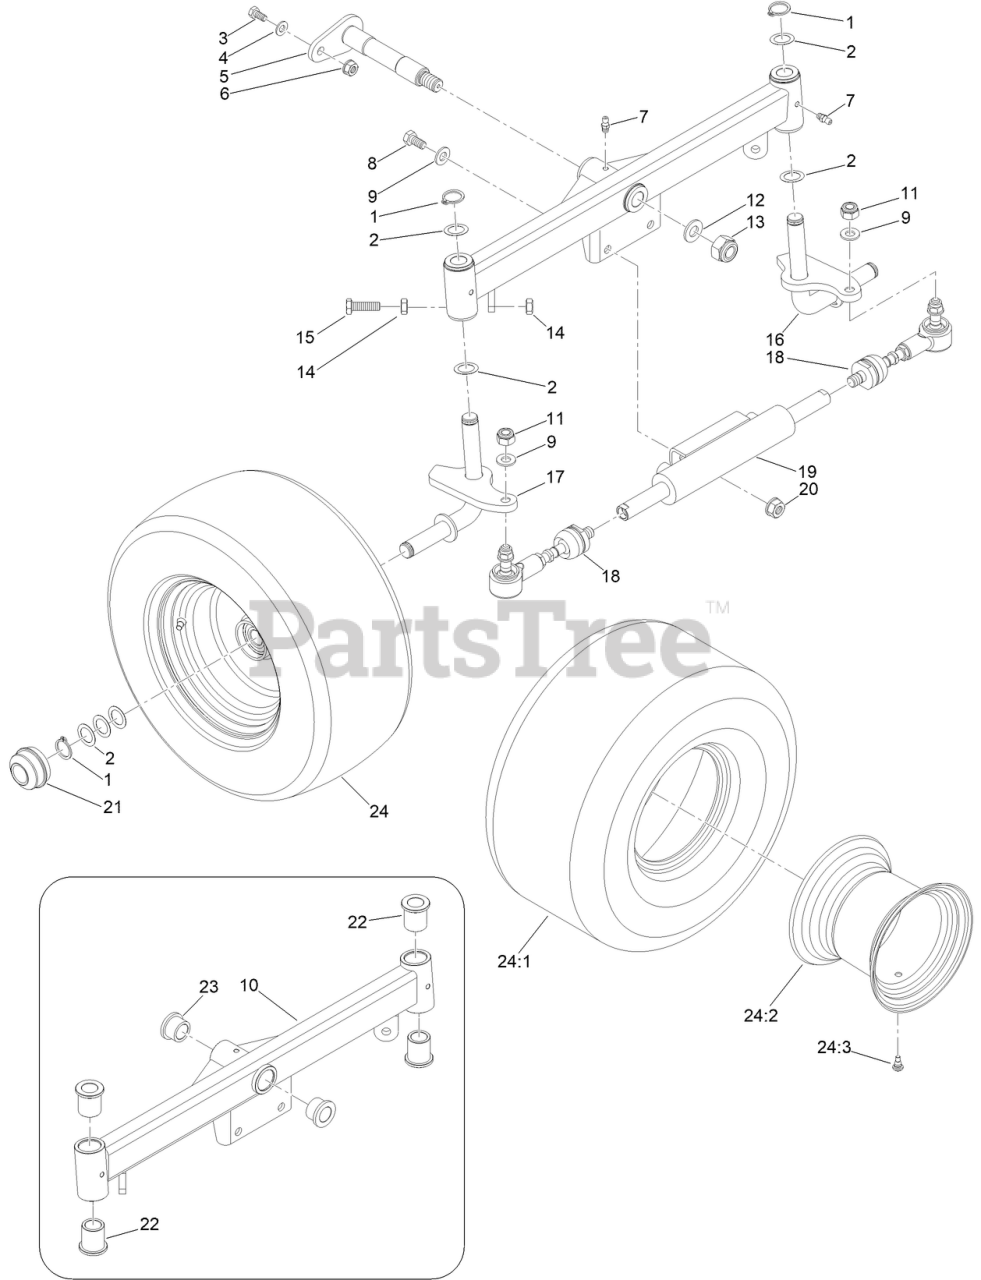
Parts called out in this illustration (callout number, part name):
1	RETAINER
2	SPACER
4	WASHER
5	PIVOT, REAR AXLE
7	FITTING-GREASE
9	WASHER
10	REAR AXLE
13	WASHER
15	SCREW, HH
16	SPINDLE, RH REAR WHEEL
17	SPINDLE, LH REAR WHEEL
18	ARTICULATION
21	COVER, REAR WHEEL HUB
22	BUSHING
23	BUSHING
24	REAR WHEEL ASM
24:3	VALVE-TIRE
